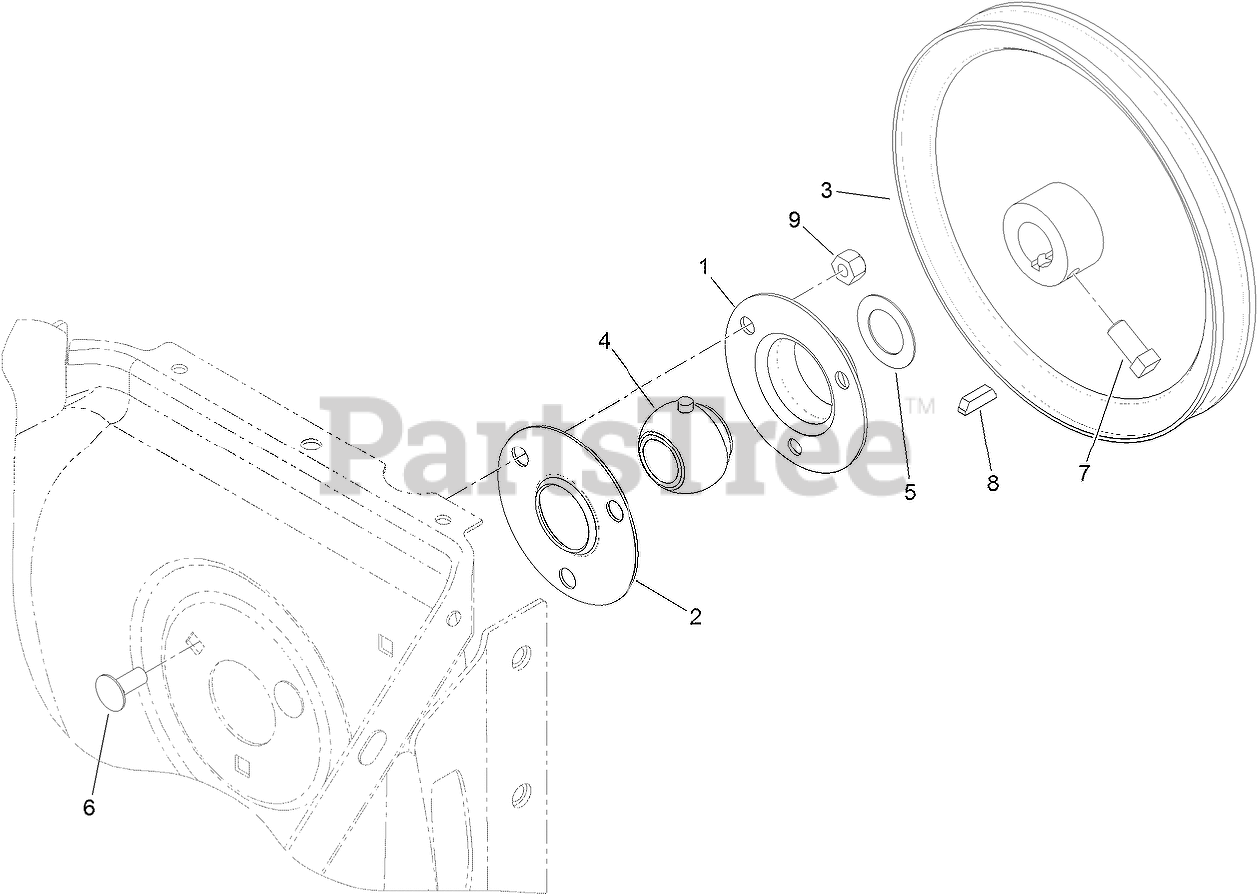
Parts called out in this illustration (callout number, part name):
1	FLANGE-CUP, BEARING
2	FLANGE-CUP, BEARING
3	PULLEY-IMPELLER
4	BEARING-BALL
5	WASHER-THRUST
6	SCREW-CARR
7	SCREW-SET, SQH
8	KEY-WOODRUFF
9	NUT-LOCK, NI
